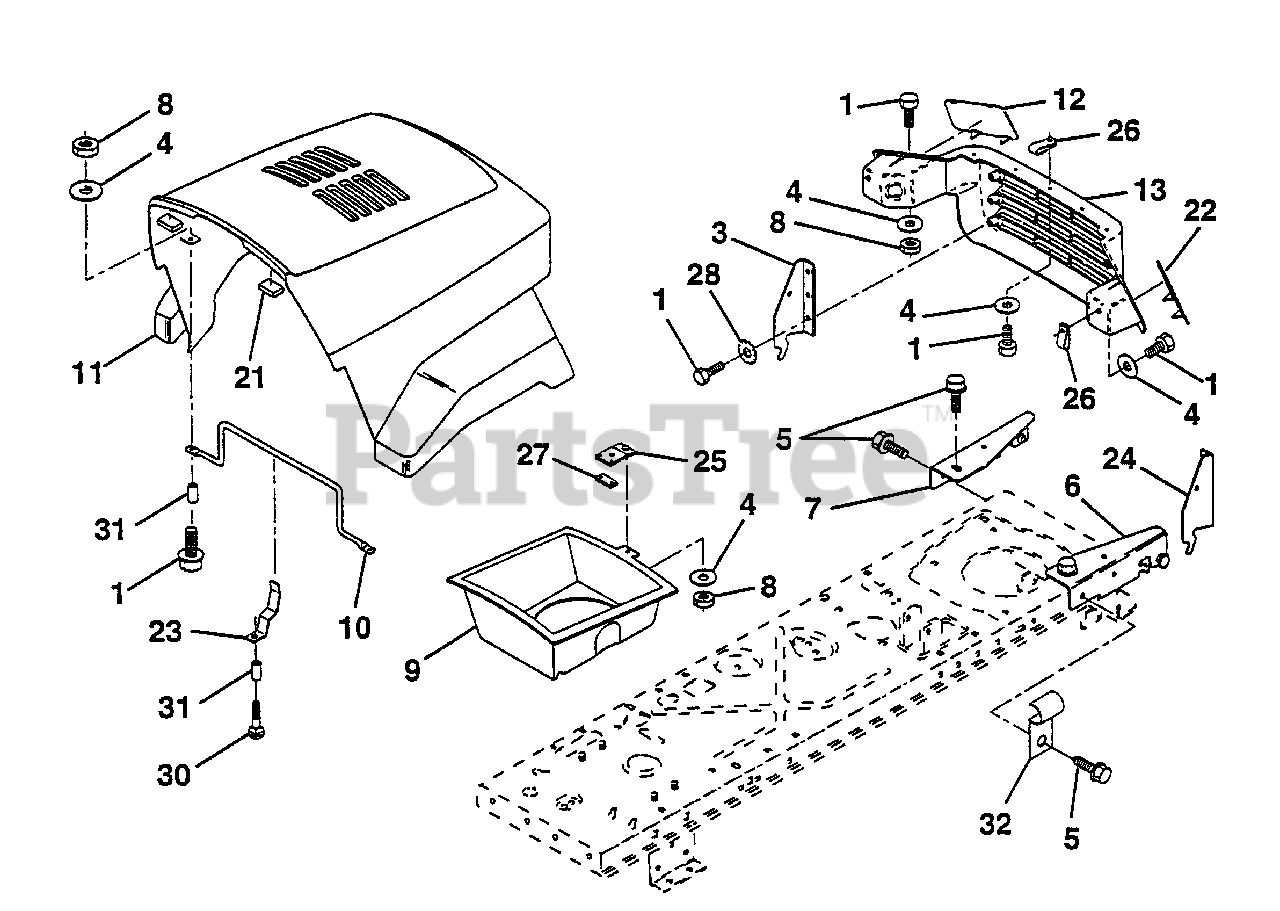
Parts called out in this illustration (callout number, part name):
1	Bolt Fin Hex 1/4-20 x 5/8
3	Bracket Pivot Hood LH
4	Washer 9/32 x 3/4 x 16 Ga.
5	Screw Thdrol 5/16-18 x 3/4
6	Bracket Asm. Pivot Hood RH
7	Bracket Asm. Pivot Hood LH
8	Nut Keps 1/4-20
9	Duct Air Hood
10	Brace Hood
13	Grille
21	Bumper Hood
23	Latch Hood
24	Bracket Pivot Hood RH
25	Clip Asm. Duct Air
26	Clip Tinnerman
27	Clip Tinnerman
28	Washer Lock Ext Tooth
30	Bolt Hex Fin 1/4 - 20 UNC x 1-1/2
31	Spacer
32	Clip Line Fuel
